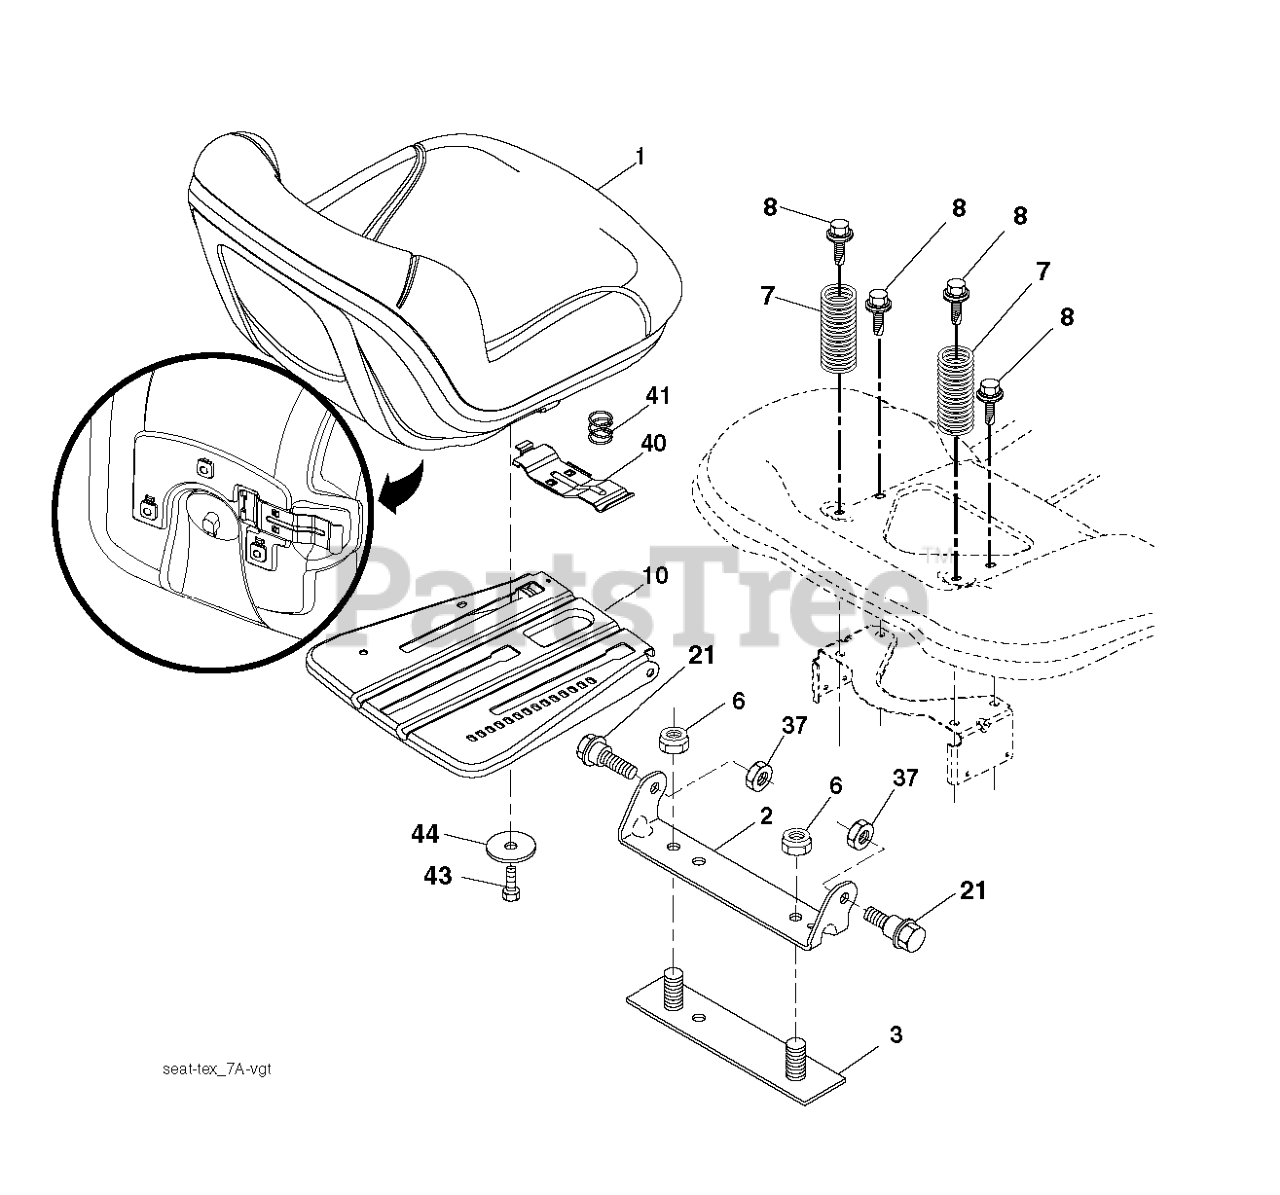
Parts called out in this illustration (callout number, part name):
1	SEAT.TH130.GRY.MILSCO.
2	BRKT.PIVOT.FENDER
3	STRAP
6	NUT
7	SPRING COMPRESSION
8	BOLT.5/16-18UNCX3/4 W/SEMS.BLK
10	PAN.ASM.SEAT.3PT
21	BOLT.SHOULDER.5/16-18
37	NUT.71038.31-18.HEX.NYLOCK
40	HANDLE.SLIDE.SEAT.TEX.BLACK
41	SPRING.LATCH.SEAT.TEX
44	WASHER 13/32 X 2-3/8 X 12GA
